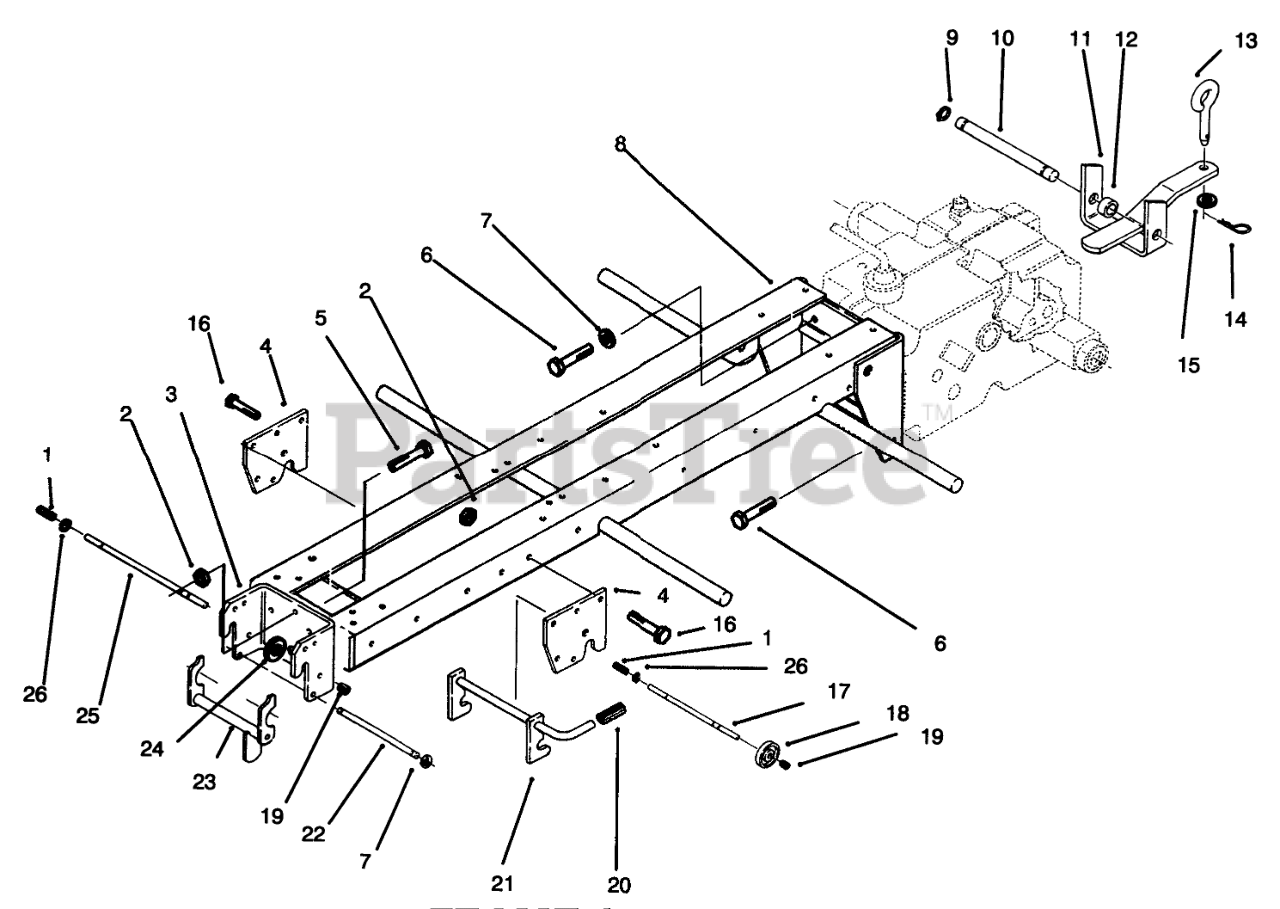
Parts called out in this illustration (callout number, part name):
1	SPRING
2	NUT-LOCK, NI
3	Front Hitch
4	Hitch Plate
5	BOLT-CARR
6	SCREW-HH
7	WASHER-LOCK
8	WELD FRAME R
9	E-RING
10	PIN-STATIONARY HITCH
11	Hitch
12	SPACER
13	PIN-TOOL
14	PIN-HAIR
15	WASHER-FLAT
16	SCREW-HH
18	ROD-LOCK
19	CAP-ROD, PLUNGER
20	GRIP
21	MID HITCH ASM
22	ROD-LATCH PIVOT
23	LATCH
25	ROD-LOCK
26	RING-RETAINING
